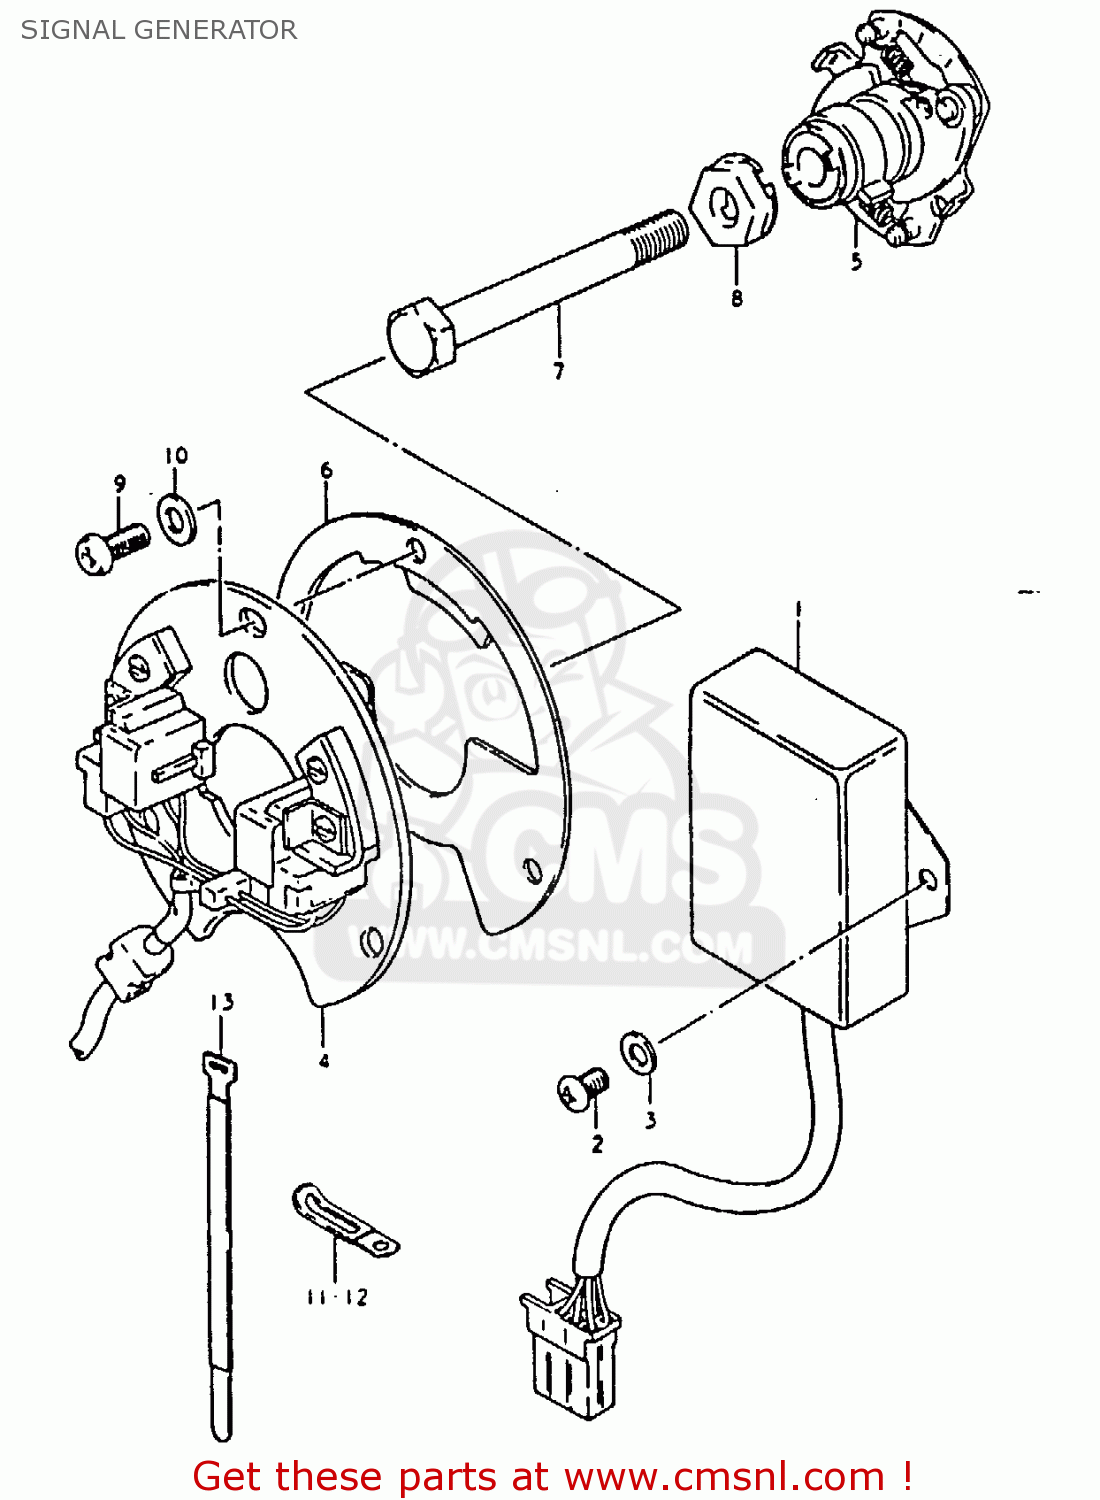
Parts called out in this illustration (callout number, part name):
1	IGNITER UNIT
2	SCREW
3	WASHER
4	SIGNAL GENERATOR ASSEMBLY
5	GOVERNOR ASSEMBLY
6	PLATE,TIMING
7	BOLT
8	WASHER
9	SCREW(5X12)
10	WASHER
11	CLAMP L:35
12	CLAMP
13	CLAMP
